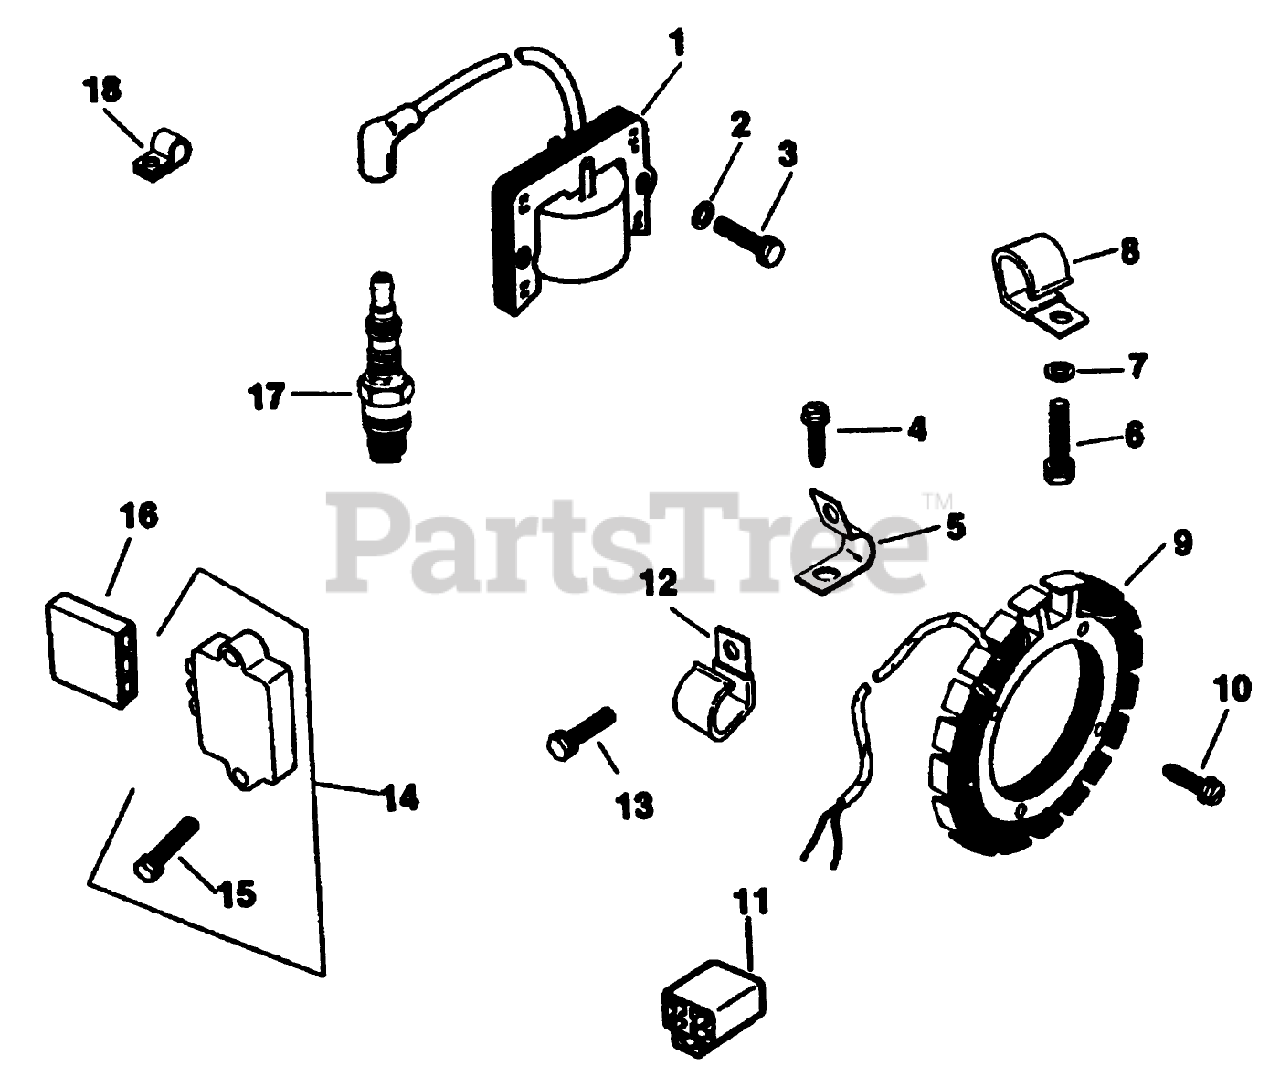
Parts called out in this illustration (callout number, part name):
1	KOHLER 47-584-02
2	KOHLER X-25-79
3	KOHLER X-156-1
4	KOHLER X-67-59
5	KOHLER X-728-1
6	KOHLER X-67-83
7	KOHLER X-25-72
8	Clip
9	KOHLER 237878
10	KOHLER X-67-51
11	KOHLER 48-155-01
12	CLIP
13	SCREW-HH
14	KOHLER 41-403-05
15	KOHLER X-132-4
16	KOHLER 236602
17	KOHLER 235041-5
18	KOHLER 210281
